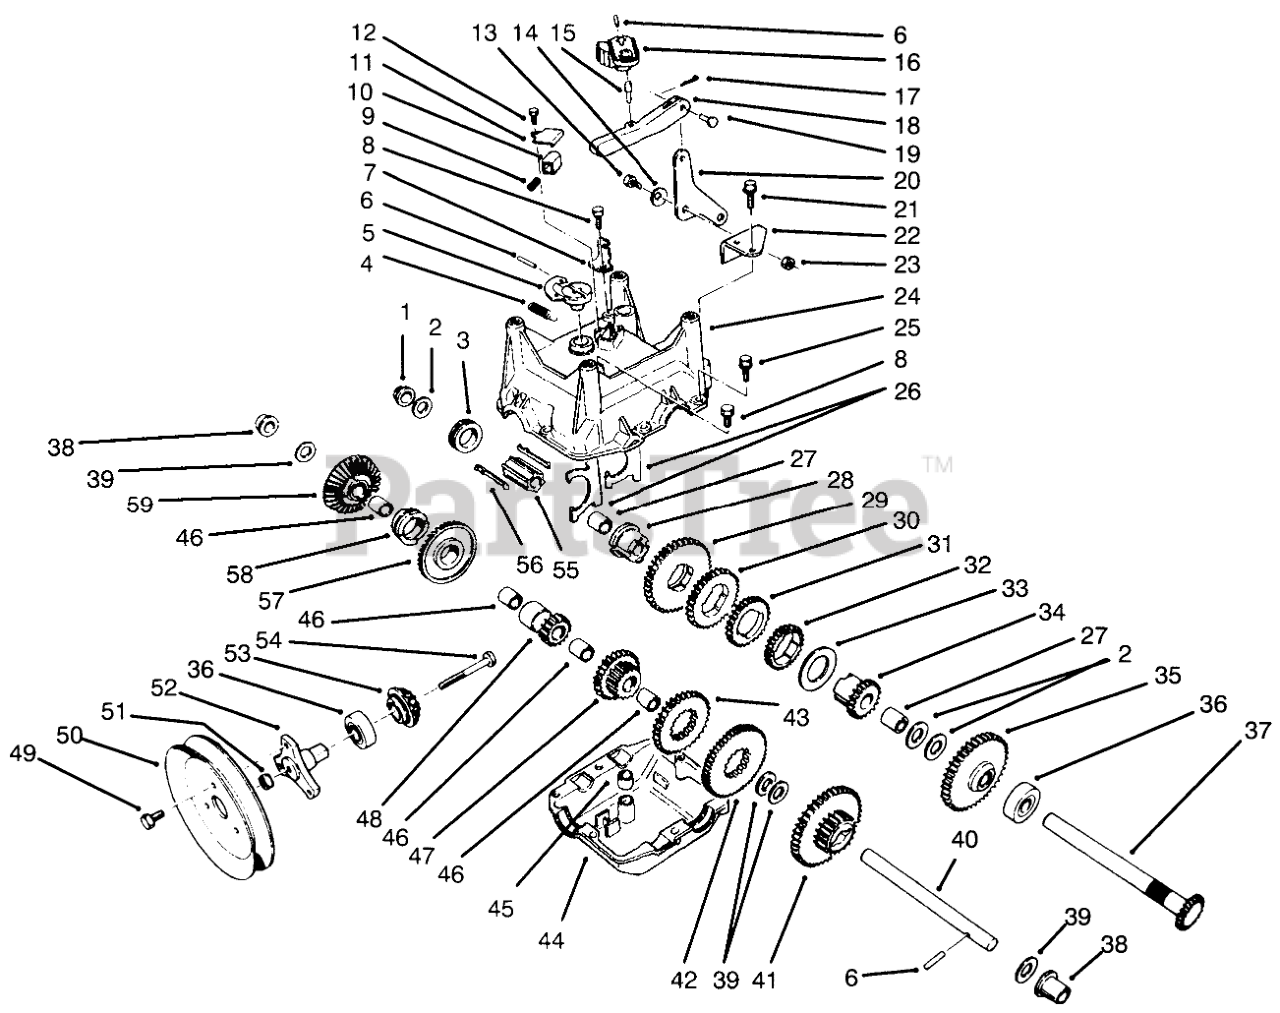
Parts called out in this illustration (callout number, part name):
1	BUSHING-FLANGE, OUTPUT
2	BEARING-THRUST
3	COLLAR-SHIFT
4	SPRING-EXTENSION
5	LEVER
6	PIN-SPRING
7	BRACKET-CABLE
8	SCREW-HWH
9	SPRING-DETENT
10	BUTTON-DETENT
11	COVER-DETENT
12	SCREW-HWH
13	SCREW-SHOULDER
14	WASHER-CURVED
15	PIN-LINK, GEAR SHIFT
16	LEVER-SHIFT, GEAR
17	PIN-COTTER
18	LINK-SHIFT, GEAR
19	PIN-CLEVIS
20	BELLCRANK
21	SCREW-HWH
22	BRACKET-BELLCRANK
23	NUT-LOCK, NI
24	GEARCASE-UPPER, CASING
25	SCREW-HWHTF
26	YOKE-SHIFT
27	BUSHING-OUTPUT
28	SLEEVE-GEAR
29	GEAR-45 T
30	GEAR-34 T
31	GEAR-27 T
32	GEAR-29 T
33	WASHER-THRUST
34	GEAR-SLEEVE, 19 T
35	GEAR-41 T
36	BEARING-BALL
37	SHAFT-OUTPUT
38	BUSHING-INTERMEDIATE
39	WASHER-THRUST
40	SHAFT-INTERMEDIATE
41	GEAR-19/41 T
42	GEAR-51 T
43	GEAR-33 T
44	GEARCASE-LOWER, CASING
45	BUSHING-YOKE
46	Bushing-Output
47	GEAR-26 T
48	GEAR-BEVEL, 15 T
49	SCREW
50	TRACTION-SHEAVE, HALF
51	NUT-HHF
52	HUB-PULLEY
53	PINION-BEVEL
54	SCREW-HH
55	SLEEVE-SHIFT
56	KEY-SHIFT
57	GEAR-BEVEL, 36 T
58	COLLAR-SHIFT
59	Gear-Bevel Reverse 36T (Incl. Ref. #46)
